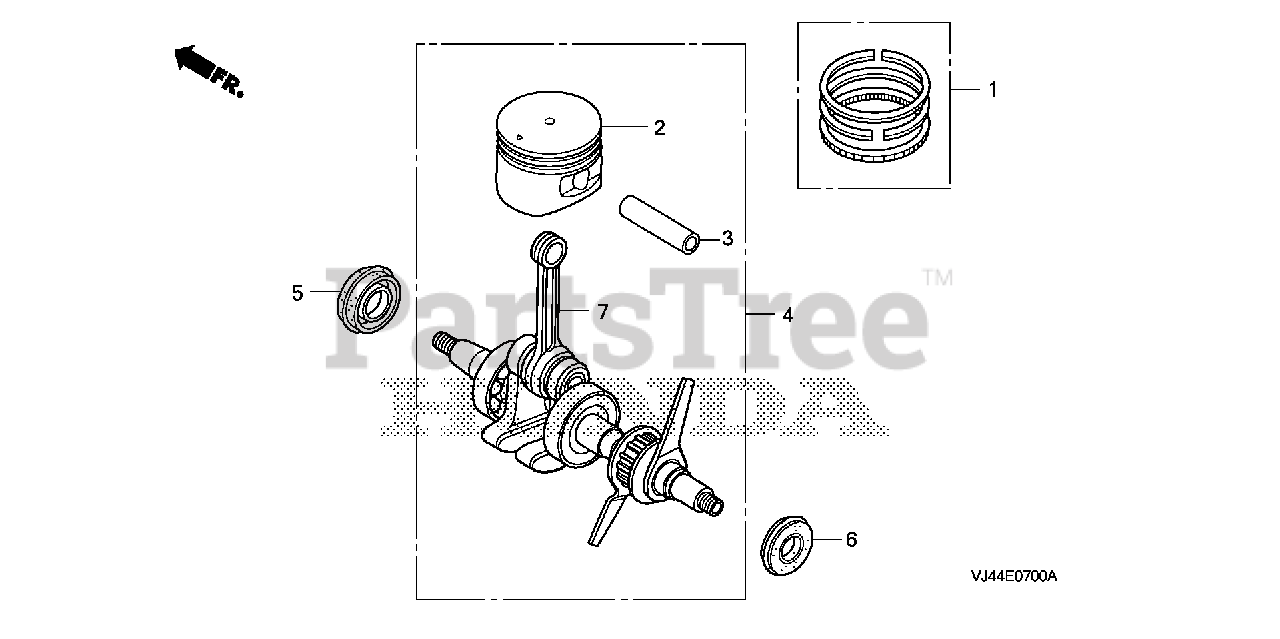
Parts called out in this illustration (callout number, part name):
1	RING SET, PISTON
1	RING SET, PISTON (TPR)
2	PISTON
2	PISTON (STD)
3	PIN, PISTON
4	CRANKSHAFT
5	OIL SEAL (12X24X5)
6	OIL SEAL (10X20X5) (NA USE ALT:91212-Z3E-003)
6	OIL SEAL (10X20X5)
7	CRANKSHAFT
